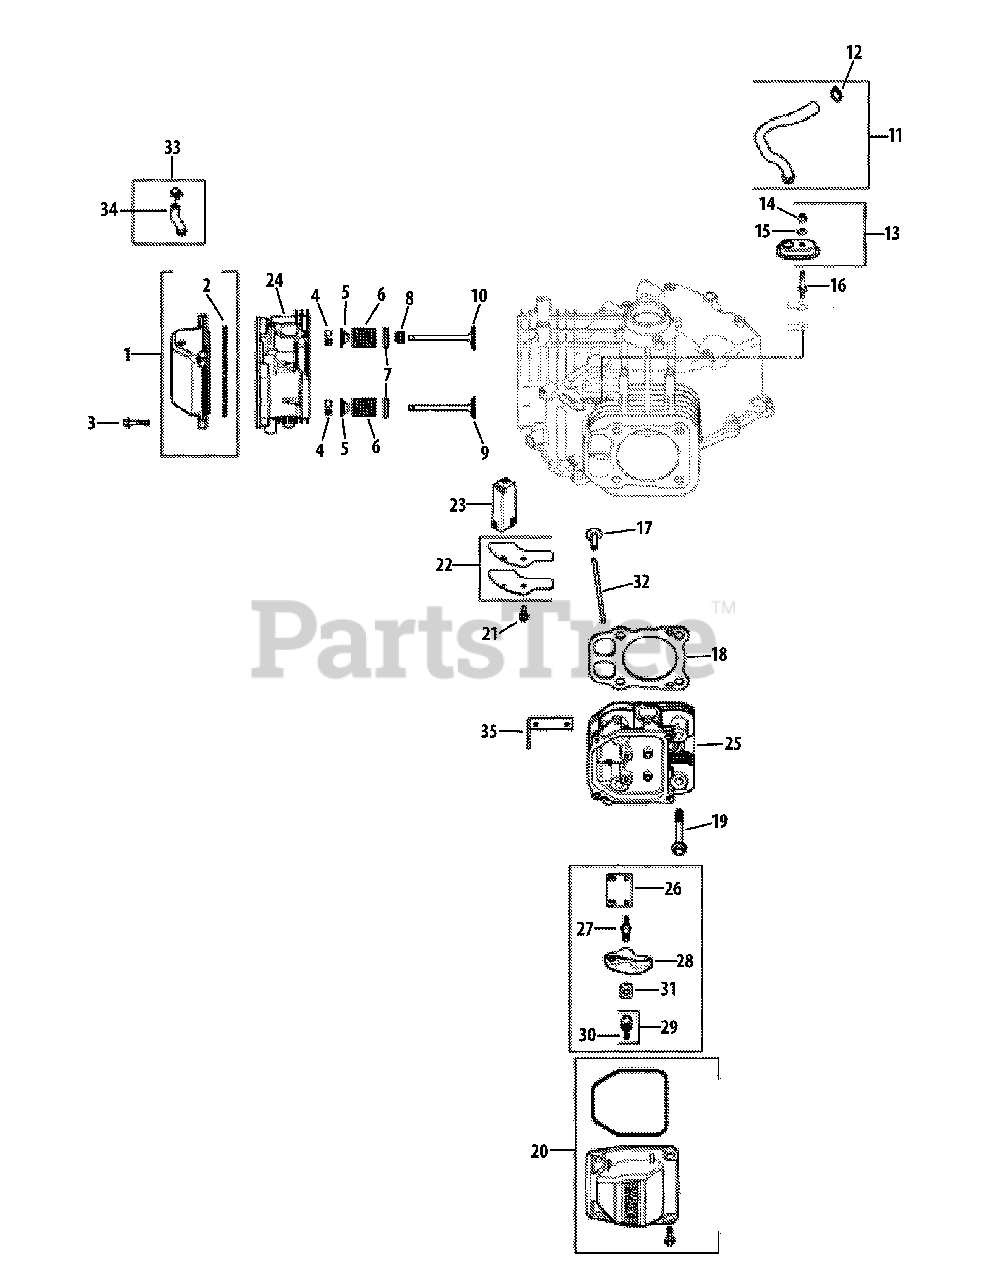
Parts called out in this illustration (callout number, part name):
1	Breather Valve Cover Kit (Inc. #2)
2	Valve Cover O-Ring
3	Flange Screw, M6 x 1.0 x 30
4	Retainer Kit
5	Valve Spring Cap
6	Valve Spring
7	Spring Retainer
8	Valve Stem Seal
9	Exhaust Valve (STD)
10	Intake Valve (STD)
11	Breather Hose Kit (Inc. #12)
12	Hose Clamp, 1.2
13	Housing Breather Kit (Inc. #14 & 15)
14	Lock Nut, M5 x 8
15	Sealing Washer
16	Breather Cover Stud
18	Cylinder Head Gasket Kit
19	Flange Screw, M10 x 1.5 x 90
20	Valve Cover Kit (Plain)
21	Flange Screw, M6 x 1.0 x 16
22	Breather Cover
23	Breather Filter
24	Cylinder Head Assembly Kit, #1
25	Cylinder Head Assembly Kit, #2
29	Hex Nut Assembly (Inc. #30)
31	Rocker Arm Pivot
33	Fuel Pump Hose Kit (Inc. #34)
35	Lifting Strap
